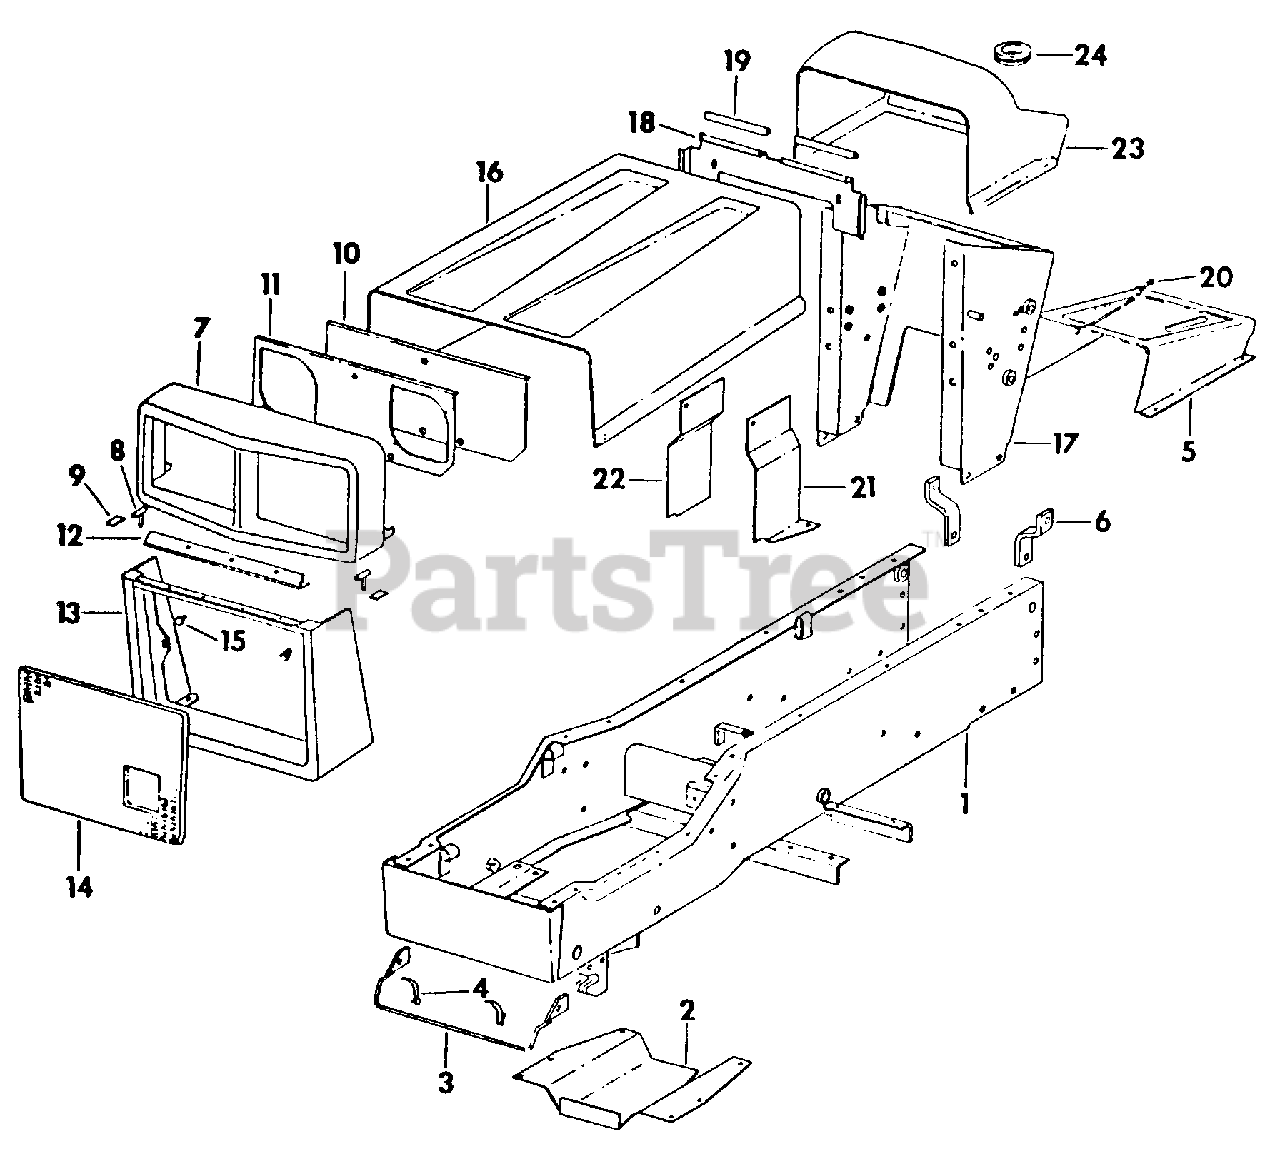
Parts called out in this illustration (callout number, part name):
1	Frame Assy
2	Shield, Frame Lower
3	Hitch Assy, Quick
4	Spring, Latch
5	Cover w/Product Graphic, Frame
6	Bracket, Trans Mtg
7	Grille, Hood Extension
8	Bolt Assy, Tee
9	Bumper, Grille
10	Panel, Grille
11	Panel, Headlight
12	Hinge, Hood Pivot
13	Housing, Grille
14	Insert, Grille
15	Spring, Hold Down
16	Hood Assy
17	Pedestal Assy, Instrument Panel
18	Support, Rear Hood
19	Bumper, Hood
20	Latch, Hood LH
21	Panel, Extension LH
22	Panel, Extension RH
23	Cowl, Instrument Panel
24	Grommet, Instrument Panel
